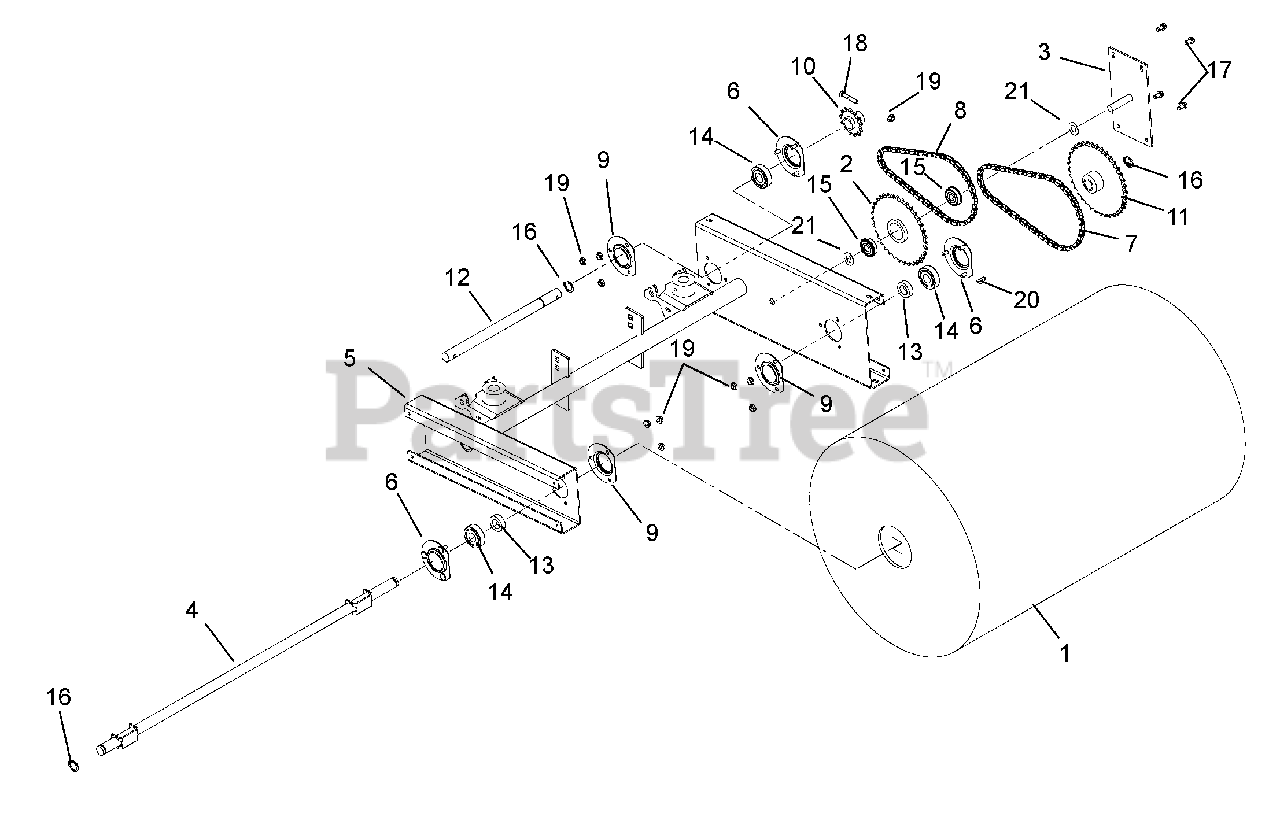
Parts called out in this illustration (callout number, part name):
1	BRUSH, 18"DIA X 28"WIDE
2	SPROCKET, REDUCTION IDLER
3	PLATE, IDLER REDUCTION MOUNT
4	SHAFT, 28" BRUSH
5	FRAME, POWER BROOM
6	BEARING FLANGE
7	CHAIN, #40-54 LINKS
8	CHAIN, #41-50 LINKS
9	BEARING FLANGE
10	SPROCKET, DRIVE
11	SPROCKET, DRIVEN
12	SHAFT, TRANSMISSION
13	SPACER .755X1.250X.370
14	BRG-BALL .750X1.750X.50
15	BRG-BALL .50X1.38X.438 SEALED
16	RG-RTNG-EXT .689X.078
17	SCR-TAP .25-20X.50 HWH TR YWZ
18	@BLT-HEX .25-20X1.75 GR5 YWZC
19	@NUT-LK-TOP-FLG .25-20 YWZC
20	KEY-WDRF .188X.75X.313 SAE 9
21	@WSHR-FL-STL.563X1.38X.109YWZC
